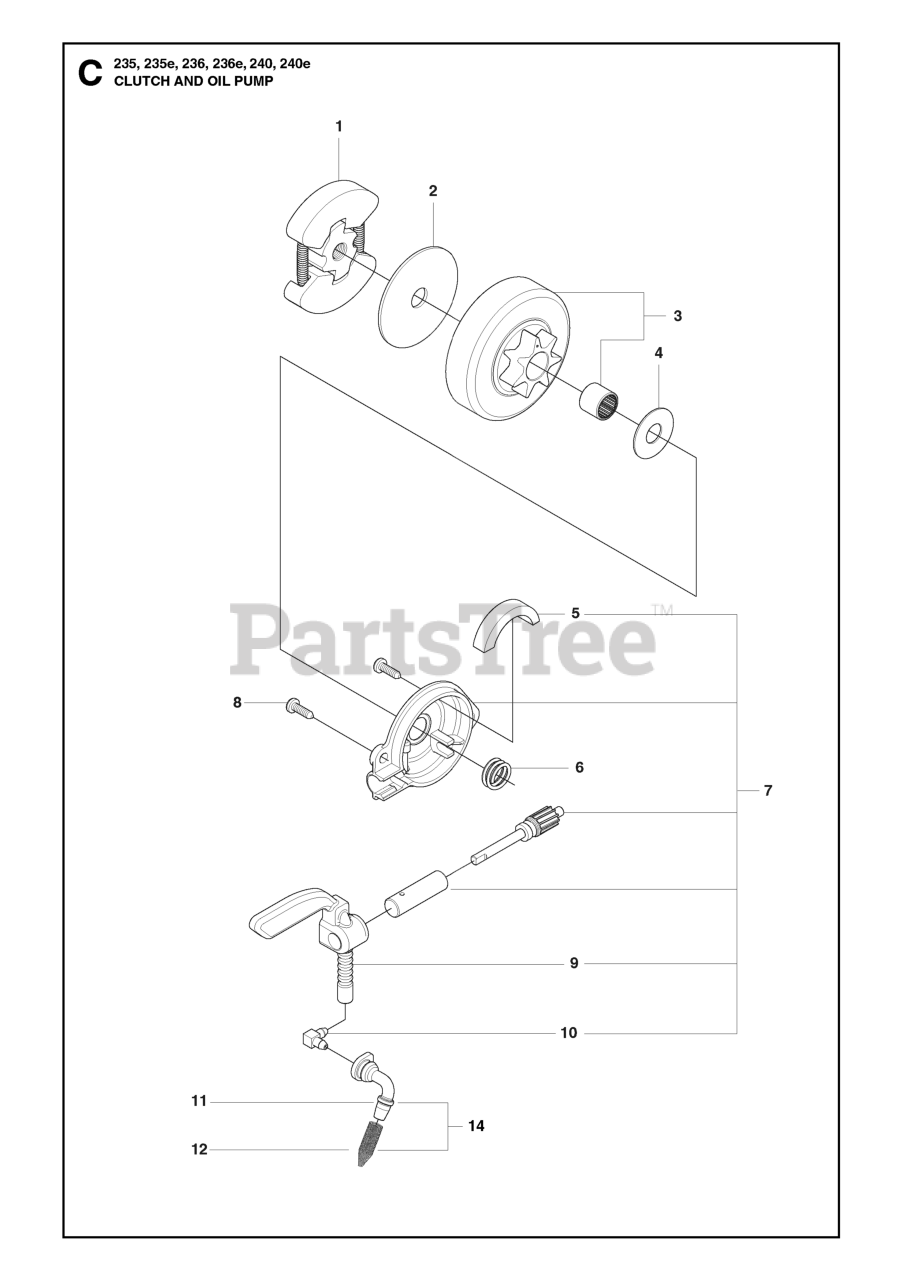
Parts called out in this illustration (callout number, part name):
1	CLUTCH ASSEMBLY
2	FRICTION DISC,CLUTCH 36/41
3	CLUTCH DRUM ASSY
3	ASSY CLUTCH DRUM .325"
7	OIL PUMP ASSY
8	SCREW 6-19X.437
11	SEAL PICKUP
12	SCREEN/FILTER
14	PICK UPS ASSY OIL TANK
